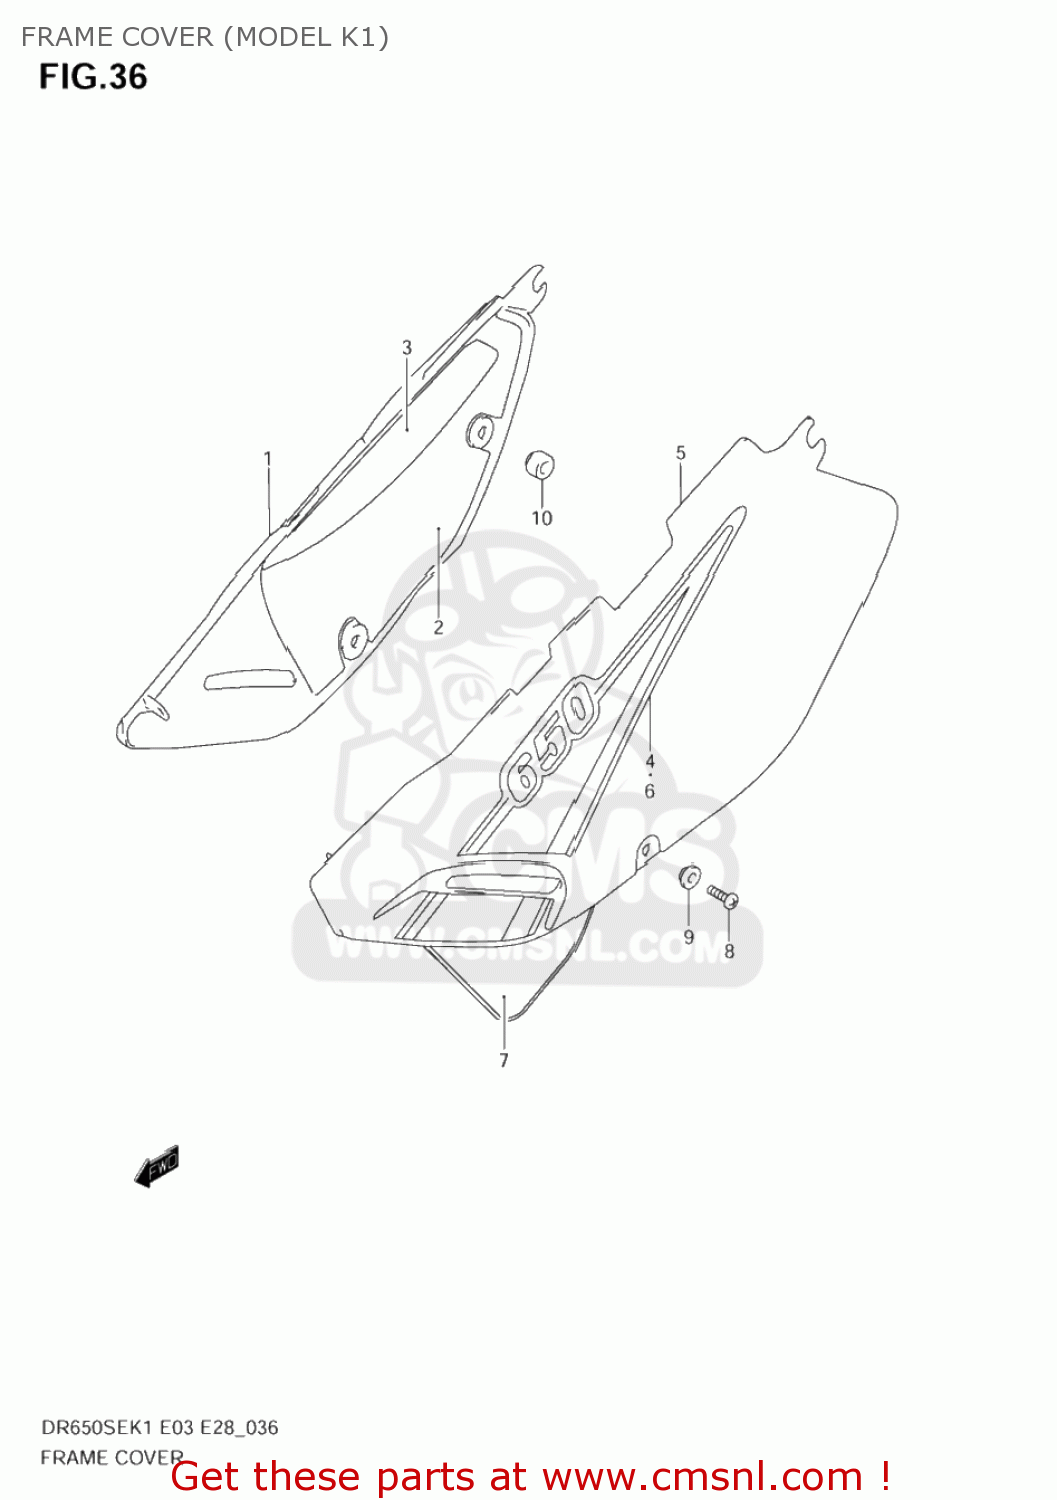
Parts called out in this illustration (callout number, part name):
1	COVER,FRAME,RIGHT
2	SHIELD,FRAME COVER,R NO.1
3	SHIELD,FRAME COVER,R NO.2
4	TAPE,FRAME COVER,R
5	COVER,FRAME,LEFT
6	TAPE,FRAME COVER,L
7	TAPE,LWR
8	SCREW
9	WASHER
10	CUSHION
